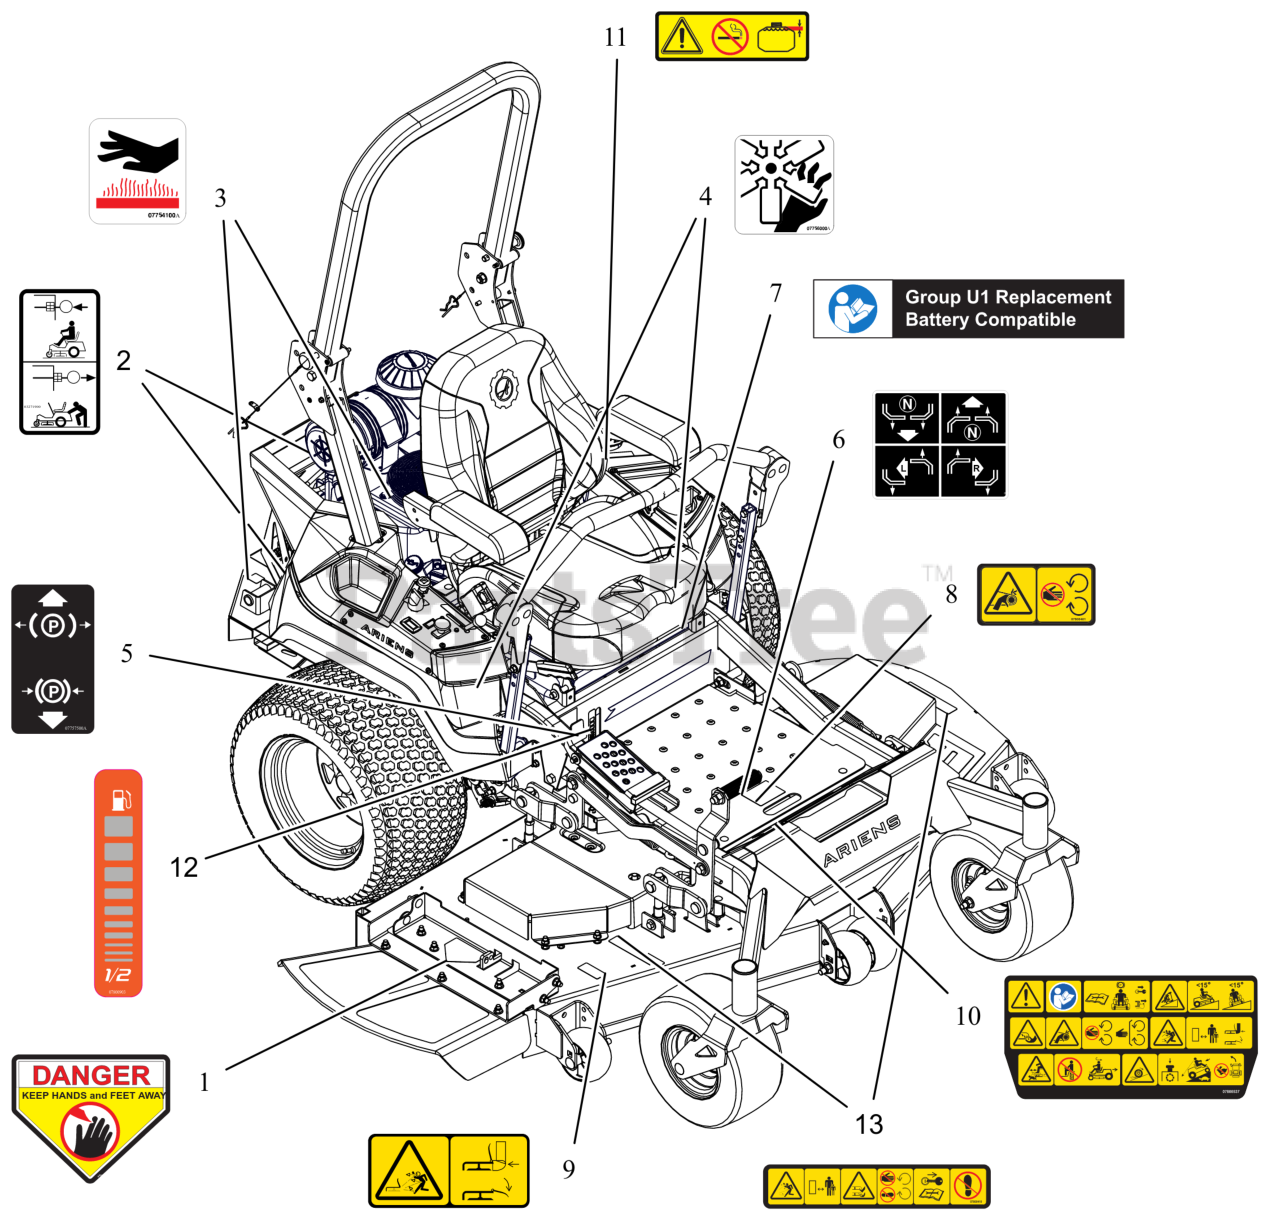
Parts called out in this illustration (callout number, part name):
1	DECAL, DANGER
2	DECAL, TRANSMISSION DISCONNECT
3	DECAL, HOT SURFACE
4	DECAL, DANGER FAN
5	DECAL, PARKING BRAKE LEVER
6	DECAL, INSTRUCTIONAL-STEERING
7	DECAL, U1 BATTERY REPLACEMENT
8	DECAL, SAFETY - GUARDING
9	DECAL, SAFETY - DECK GUARDING
10	DECAL, MAIN SAFETY
11	DECAL, FUEL WARNING
12	DECAL, ARIENS FUEL LEVEL
13	DECAL, DECK SAFETY
